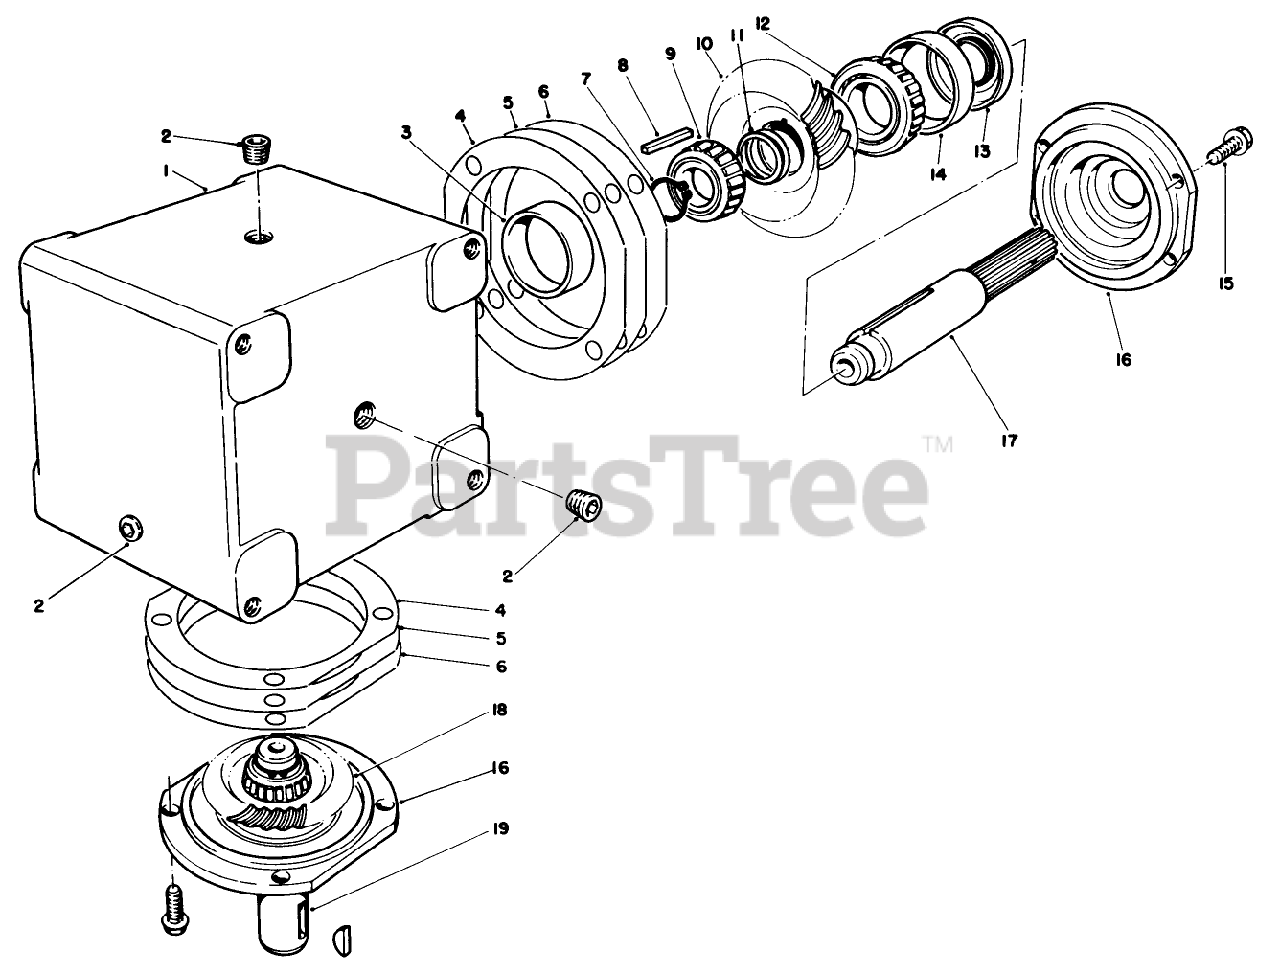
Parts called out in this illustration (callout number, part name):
1	HOUSING
2	PLUG (OBS, C/R TO 281-10)
3	Bearing Cup
4	GASKET
5	GASKET
6	GASKET
7	Ring-Retaining
8	Key
9	Cone
12	Cone
13	Seal
14	Cup
15	SCREW-HH (OBS, C/R TO 3234-5)
17	Shaft
19	Shaft
